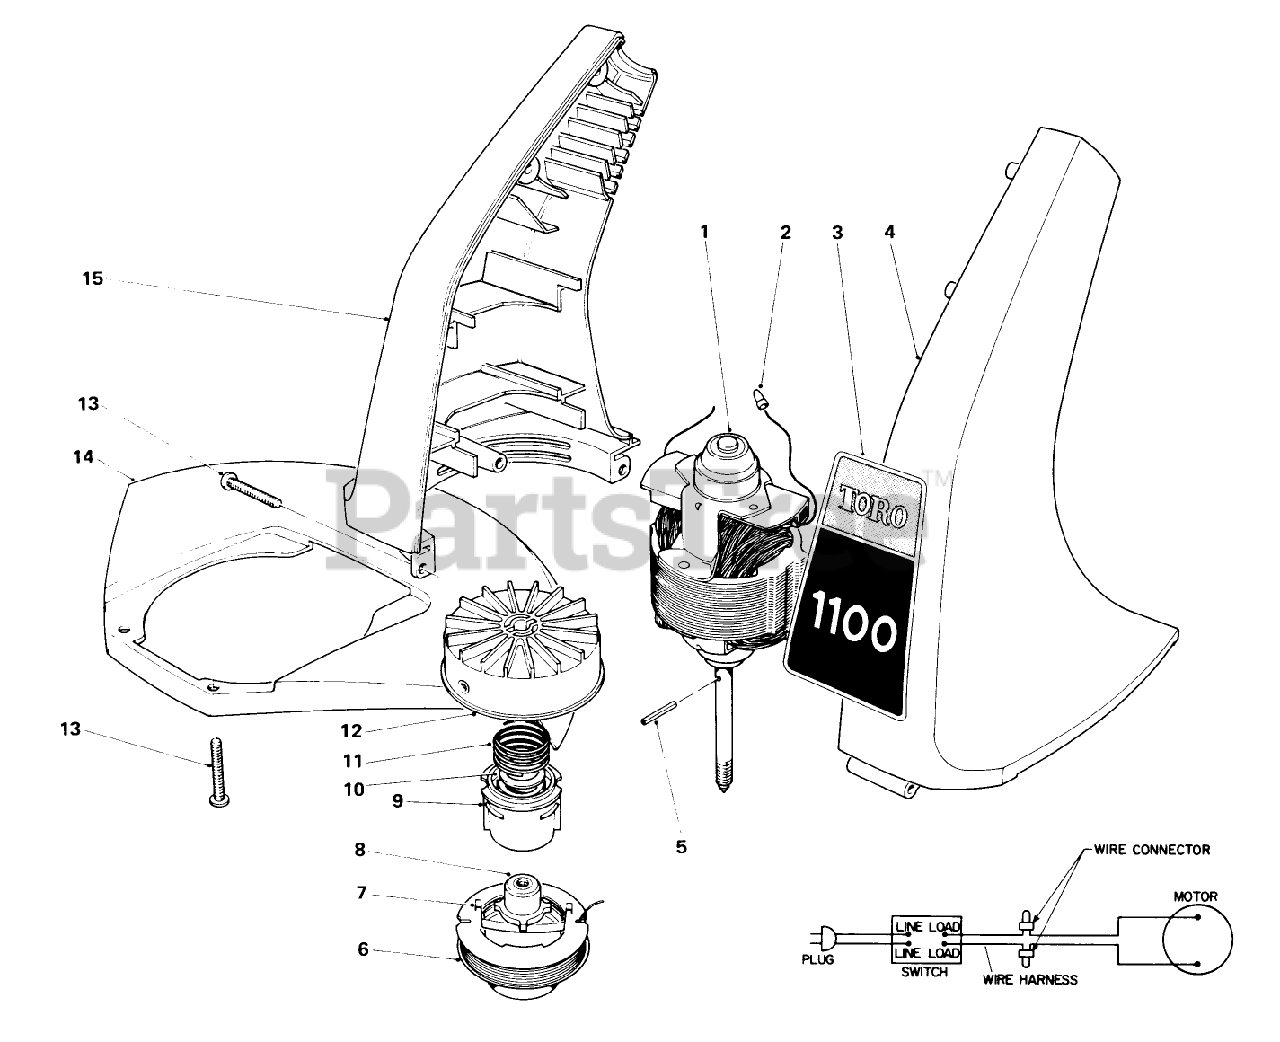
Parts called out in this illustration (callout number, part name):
1	Motor
2	CONNECTOR WIRE JOINT
3	1100 Decal
4	Housing-Left Hand
5	COIL PIN
6	Prewound Spool (Incl. Ref.#7)
7	SADDLE-SPOOL CAP
8	Driver
9	SPOOL CORE
10	WASHER-FLAT
11	SPRING COMPRESSION
12	DRUM W/EYELET
13	Screw
14	Shield
15	R.H. HOUSING, 1100
